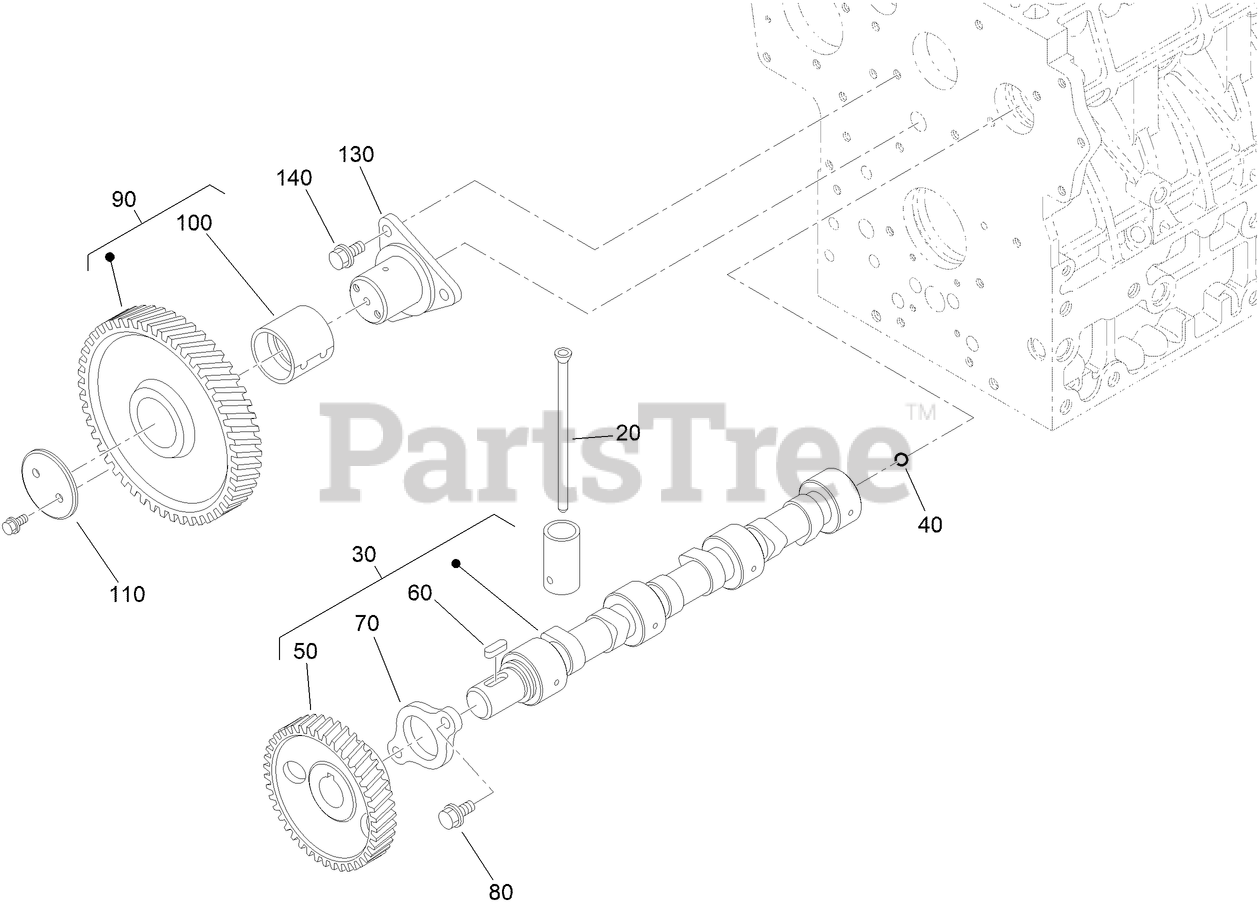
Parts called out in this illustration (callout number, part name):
20	ROD-PUSH
30	CAMSHAFT ASM
50	GEAR-CAMSHAFT
60	KEY-FEATHER
70	STOPPER-CAMSHAFT
80	BOLT-FLANGE
90	GEAR-IDLE
100	BUSHING-GEAR, IDLE
110	COLLAR-GEAR, IDLE
130	SHAFT-GEAR, IDLE
140	BOLT-FLANGE
